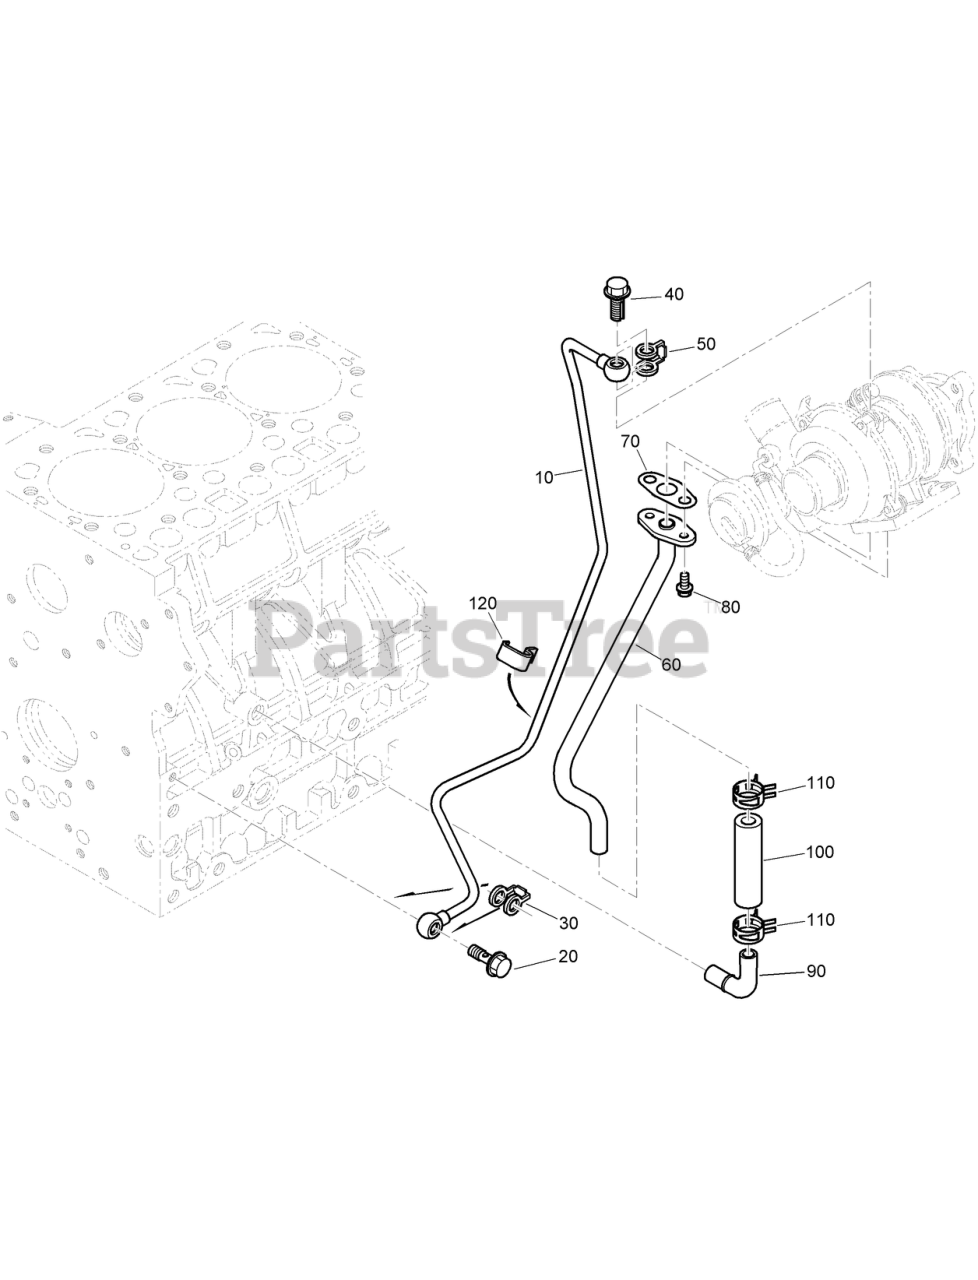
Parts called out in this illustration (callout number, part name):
20	BOLT-CONNECT
30	GASKET
40	BOLT-JOINT, EYE
50	GASKET
60	PIPE-OIL 2
70	GASKET-PIPE, OIL
80	BOLT-FLANGE
90	PIPE-OIL
100	TUBE-OIL
110	CLAMP-HOSE
120	CLAMP-PIPE
